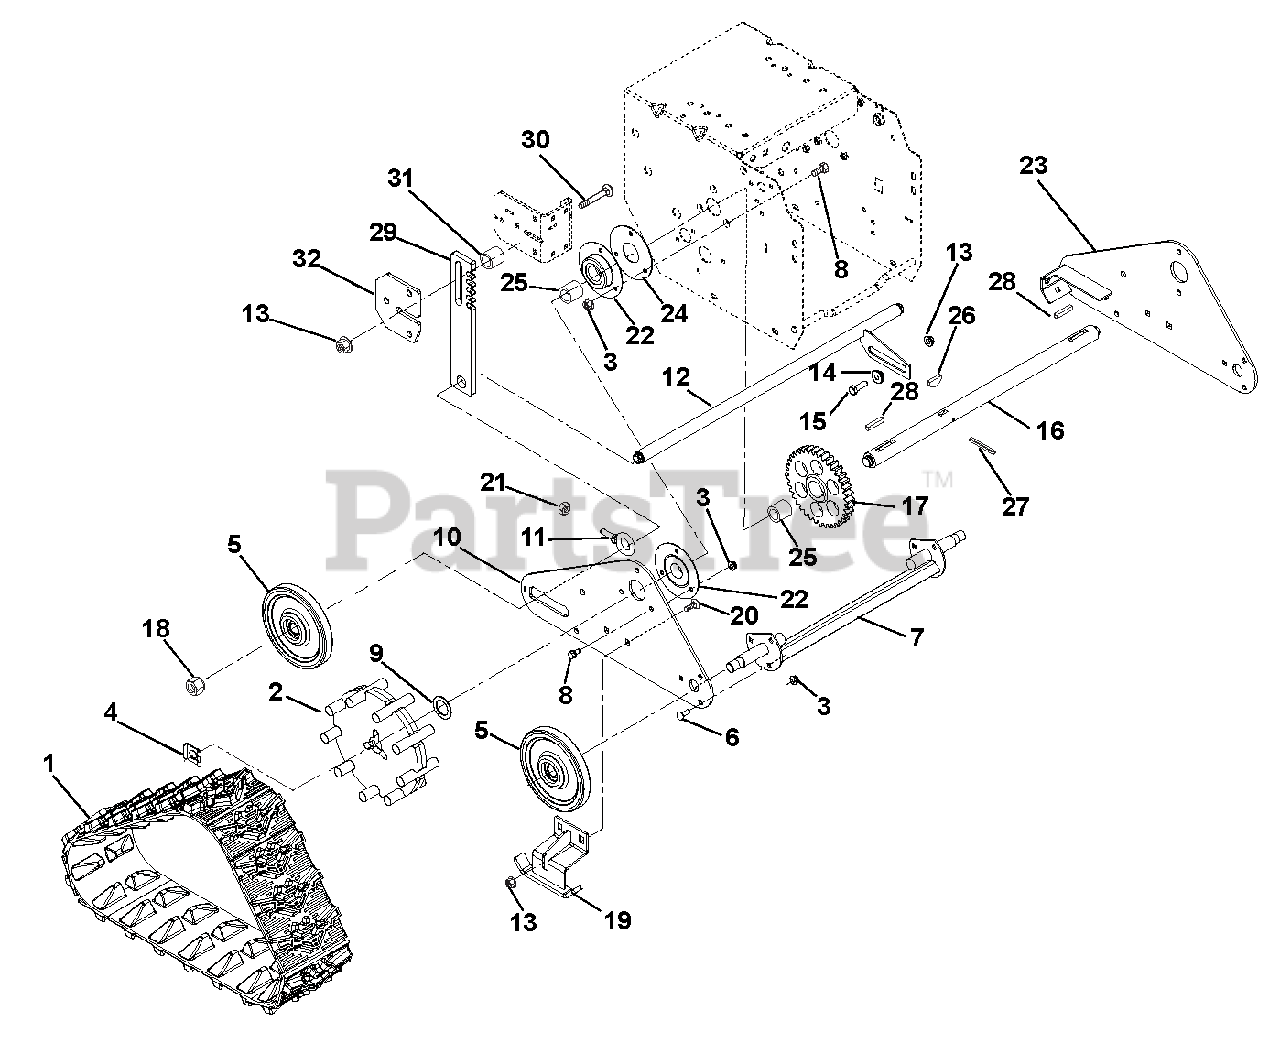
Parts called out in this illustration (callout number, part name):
1	TRACK, RUBBER
2	WHEEL, DRIVE-TRACK
3	@NUT-LK-TOP-FLG .25-20 YWZC
4	CLIP, SNAP .625 DIA
5	WHEEL, BOGIE - SINGLE BEARING
6	@BLT-RDHDSQNK .25-20X.75 G5YZ
7	AXLE, FRONT-DELUXE TRACK
8	@BLT-HEX .25-20X.75 GR5 YWZC
9	WSHR-FL-STL 1.010X1.505X.062YZ
10	SIDE PLATE, RH-DELUXE TRACK
11	BLT-EYE .375-16X.880 YWZC
12	AXLE, REAR - DELUXE TRACK
13	@NUT-LK-TOP-FLG .31-18 YWZC
14	BSHG-FLG .325X.499X.3X.875
15	@BLT-HEX .31-18X1.00 GR5 YWZC
16	AXLE, TRACK-DELUXE
17	GEAR, SPUR
18	@NUT-LK-NYL .625-18 YWZC
19	RUNNER, GUIDE-TRACK
20	@BLT-RDHDSQNK .31-18X.75 G5YZ
21	NUT-LK-CTR-FLG .38-16 YWZC
22	BRG-FLG 1.003/1.000 3 BOLT
23	SIDE PLATE, LH-DELUXE TRACK
24	PLATE, BEARING SPACER
25	BSHG-SLV, 1.012X1.125X1.00
26	KEY-WDRF .25X.750X.313 SAE91
27	PIN-ROLL .188X1.25
28	KEY-RECT .25X.188X1.00
29	STOP, HEIGHT ADJUSTER - DELUXE
30	@BLT-RHDSHSQNK.31-18X1.25 G5YZ
31	SPACER .50 X .32 X .42
32	PLATE, HEIGHT ADJUSTER
